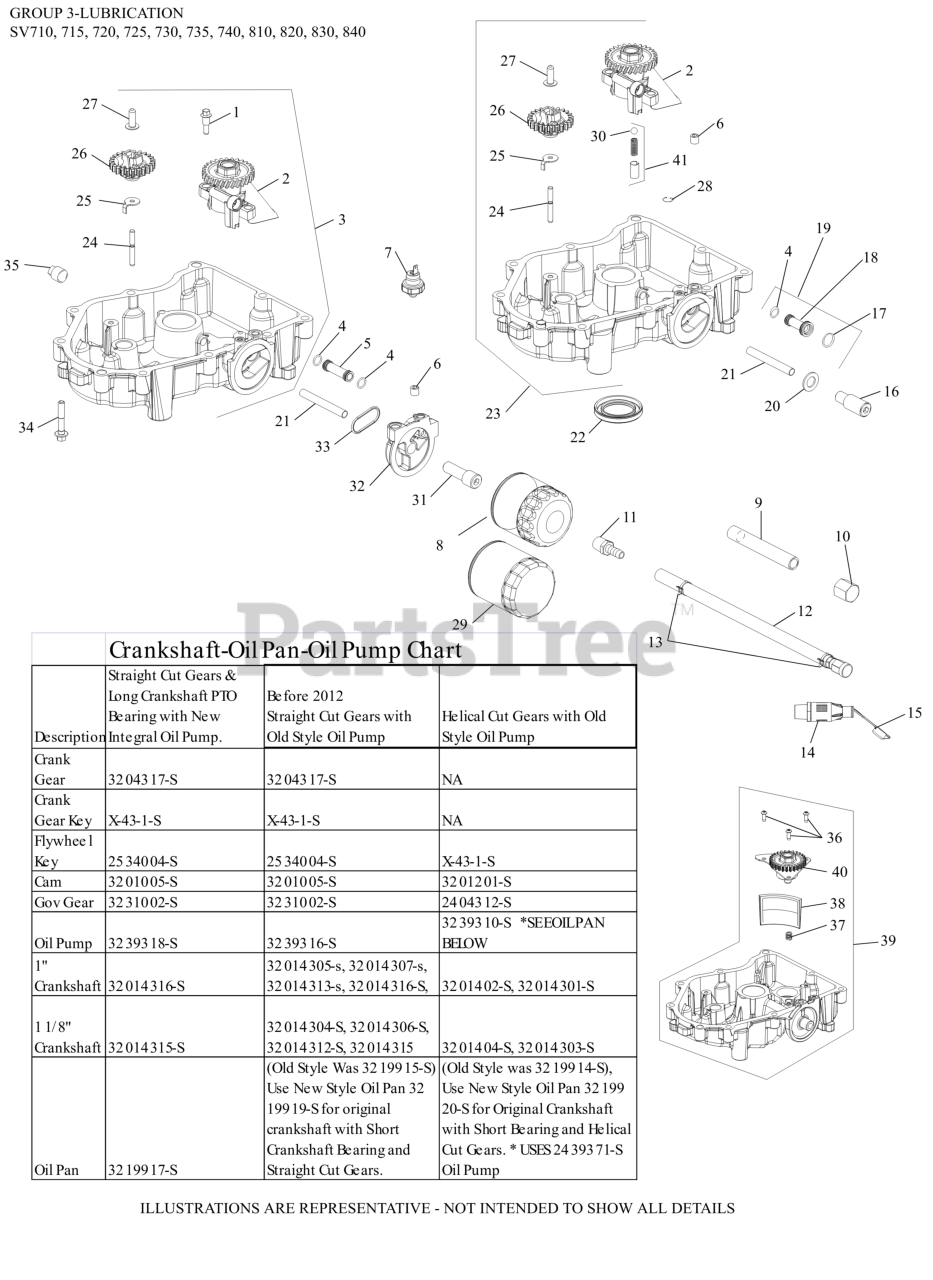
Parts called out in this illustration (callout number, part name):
1	SCREW, SHD THD FRM M6X.0X6.5
2	PUMP, OIL ASSEMBLY-DISCONTINUED
4	O-RING, OIL PICK-UP
6	PLUG, CTSK PIPE 1/8"
8	OIL FILTER
16	NIPPLE, OIL FILTER-(#DSC)
18	TUBE, OIL FEED
19	OIL FEED TUBE ASSEMBLY
20	WASHER, FLAT
21	TUBE, OIL FEED - FILTER TO PAN
23	OIL PAN ASSEMBLY - (#3219920S)
24	SHAFT, GOVERNOR GEAR
25	TAB, LOCKING
26	KIT, GOVERNOR GEAR
27	PIN, GOVERNOR REGULATING
28	RETAINER, PIN-DISCONTINUED
30	STEEL BALL
34	SCREW, FLG M8X1.25X45
35	PLUG, SQ HD PIPE 3/8"
41	KIT, OIL RELIEF-(#DSC)
